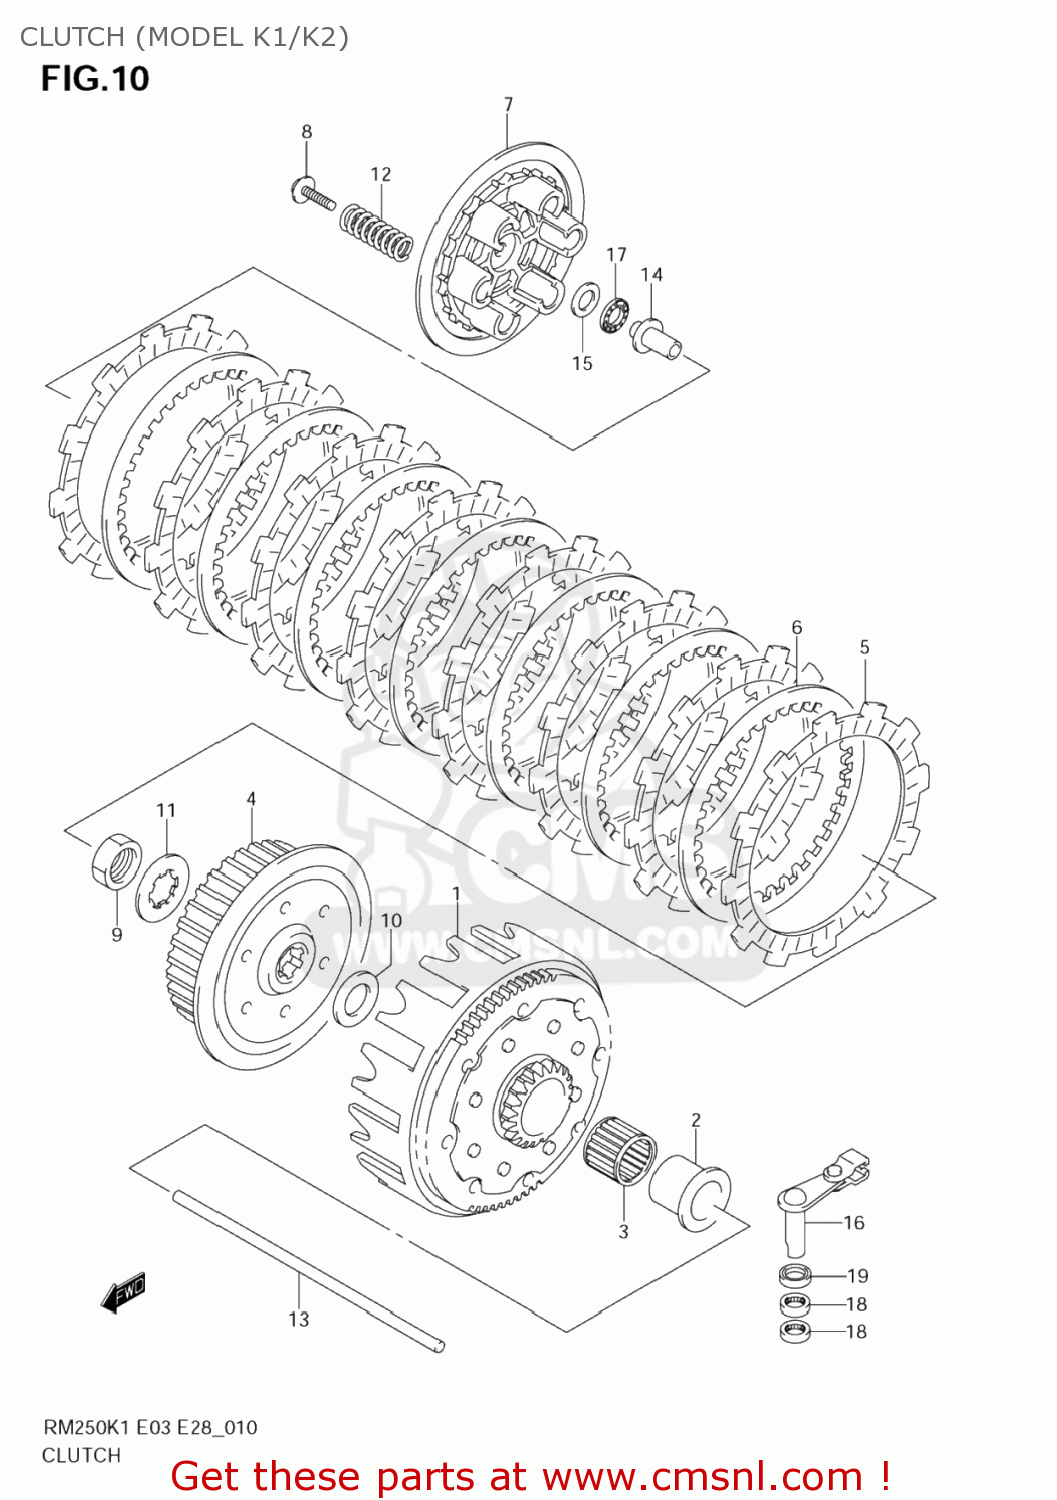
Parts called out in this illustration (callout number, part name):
1	GEAR ASSEMBLY,PRIMARY DRIVE
2	SPACER,PRIMARY DRIVEN
3	BEARING(29X34X27)
4	HUB,CLUTCH SLEEVE
5	PLATE,CLUTCH DRIVE (NAS)
6	PLATE,CLUTCH DRIVEN (NAS)
7	DISC,CLUTCH PRESSURE
8	BOLT(5X25)
9	NUT
10	WASHER(22X38X2)
11	WASHER,LOCK
12	SPRING
13	ROD,CLUTCH PUSH
14	PIECE,CLUTCH PUSH
15	SHIM(10X20X0.5)
16	CAMSHAFT,CLUTCH RELEASE
17	BEARING(10X22X2.8)
18	BEARING(12X16X10)
19	SEAL,OIL(12X19X5)
